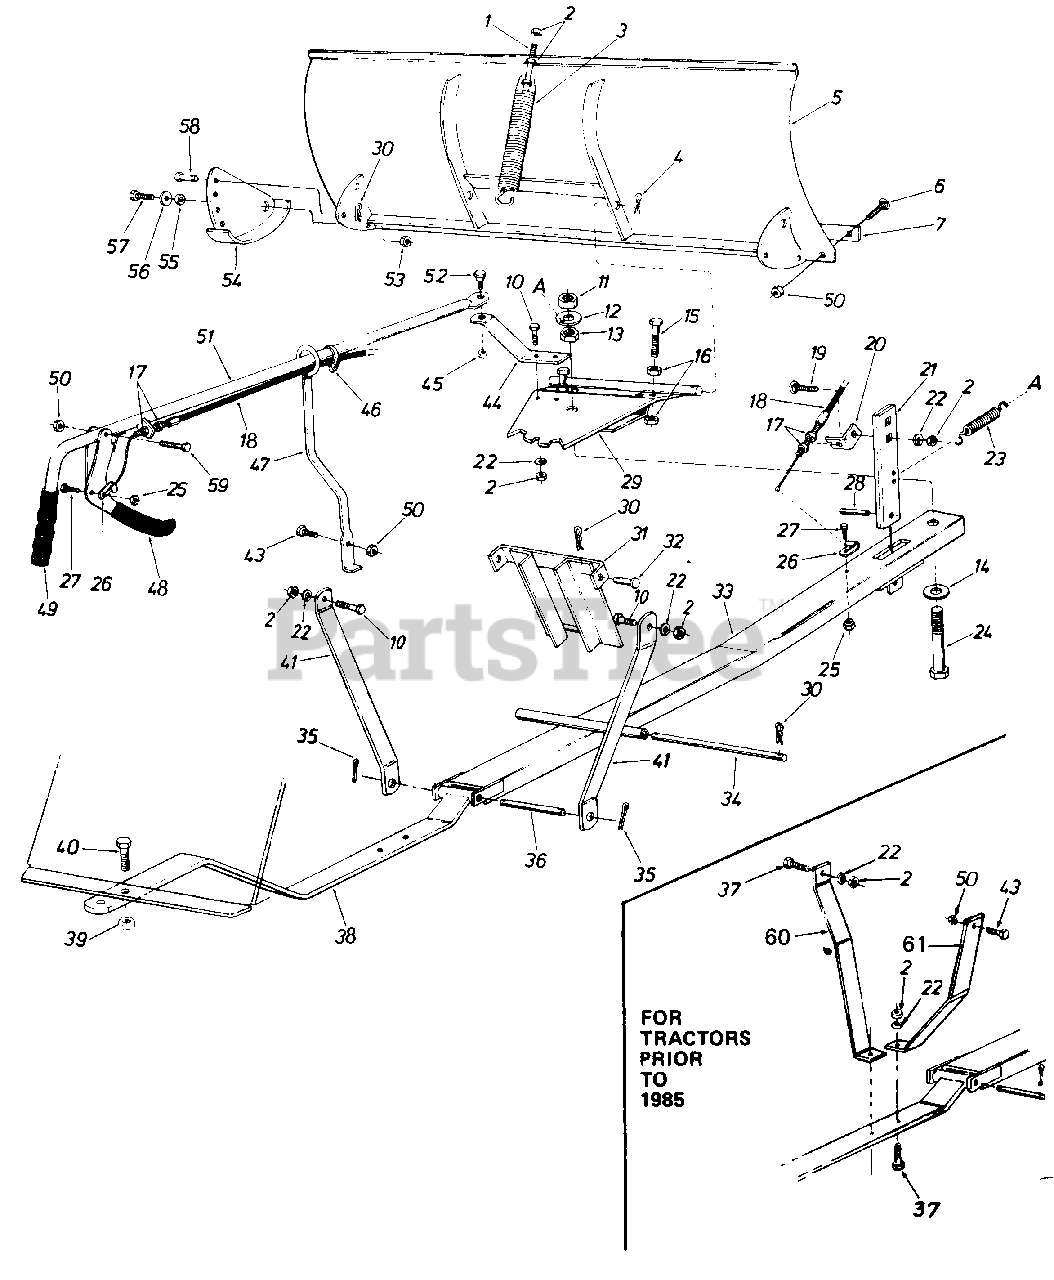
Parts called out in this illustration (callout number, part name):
1	Hex Scr. 3/8-16 x 4.50" Lg.
2	HexNut 3/8-16 Thd.
3	Blade Adjustment Spring
4	Hairpin Clip 5/32" Dia.
5	48" Blade Ass'y.
6	Carriage Bolt 5/16-18 x .75" Lg.
7	Wear Plate 48"
10	Hex Scr. 3/8-16 x 1.00" Lg.
11	Hex L.-Nut 3/4-10 Thd.
12	Fl.-Wash. .810" I.D. x 2.00" O.D.
13	Hex Jam Nut 3/4-10 Thd.
14	Fl.-Wash. .810" I.D. x 2.00" O.D.
15	Hex Scr. 1/2-13 x 2.00" Lg.
16	Hex Nut 1/2-13 Thd .
17	Hex Jam Nut 5/16- 24 Thd.
18	Control Cable Ass'y.
19	Carriage Bolt 3/8-16 x 1.25" Lg.
20	Cable Guide Bracket
21	Angle - Lock Bar
22	L.-Wash. 3/8" I.D.
23	Angle Lock Spring
24	Hex Scr. 3/4-10 x 4.00" Lg.
25	Hex L.-Nut 1/4-20 Thd.
26	Clevis Lanyard Fitting
27	Hex Scr. 1/4-20 x .75" Lg.
28	Roll Pin 1/4" Dia. x 1.00" Lg.
29	Pivot Plate Ass'y.
30	Hairpin Clip 3/32" Dia.
31	Guide Bracket Ass'y.
32	Clevis Pin 1/2" Dia. x 1.00" Lg.
33	Push Bar Ass'y.
34	Lift Shaft
35	Cotter Pin 5/32" Dia. x 1.00" Lg.
36	Pivot Shaft
37	Hex Scr. 3/8-16 x 1.25" Lg.
38	Hanger Bracket Ass'y.
39	Hex L.-Nut 5/8-11 Thd
40	Hex Scr. 5/8-11 x 1.50" Lg.
41	Hanger Link
43	Hex Bolt 5/16-18 x 1.00" Lg.
44	Blade Pivot Bracket
45	Hex L.-Nut 3/8-16 Thd.
46	Nylon Cable Tie
47	Tube Guide Ass'y.
48	Clutch Grip Ass'y.
49	Grip-3/4" Handle
50	Hex L-Nut 5/16-18 Thd.
51	Tube Handle Ass'y.
52	Shld. Scr.-Special 3/8-16 Thd.
53	Hex L.-Nut 3/8-16 Thd.
54	Skid Assembly
55	Spacer
56	Fl.-Wash. .385" I.D. x 1.00" O.D.
57	Hex Scr. 3/8-16 x4.75" Lg.
58	Clevis Pin 5/16" Dia. x .75" Lg.
59	Hex Scr. 5/16-18 x 1.50" Lg.
60	Mounting Brkt.-L.H.
61	Mounting Brkt-R.H.
